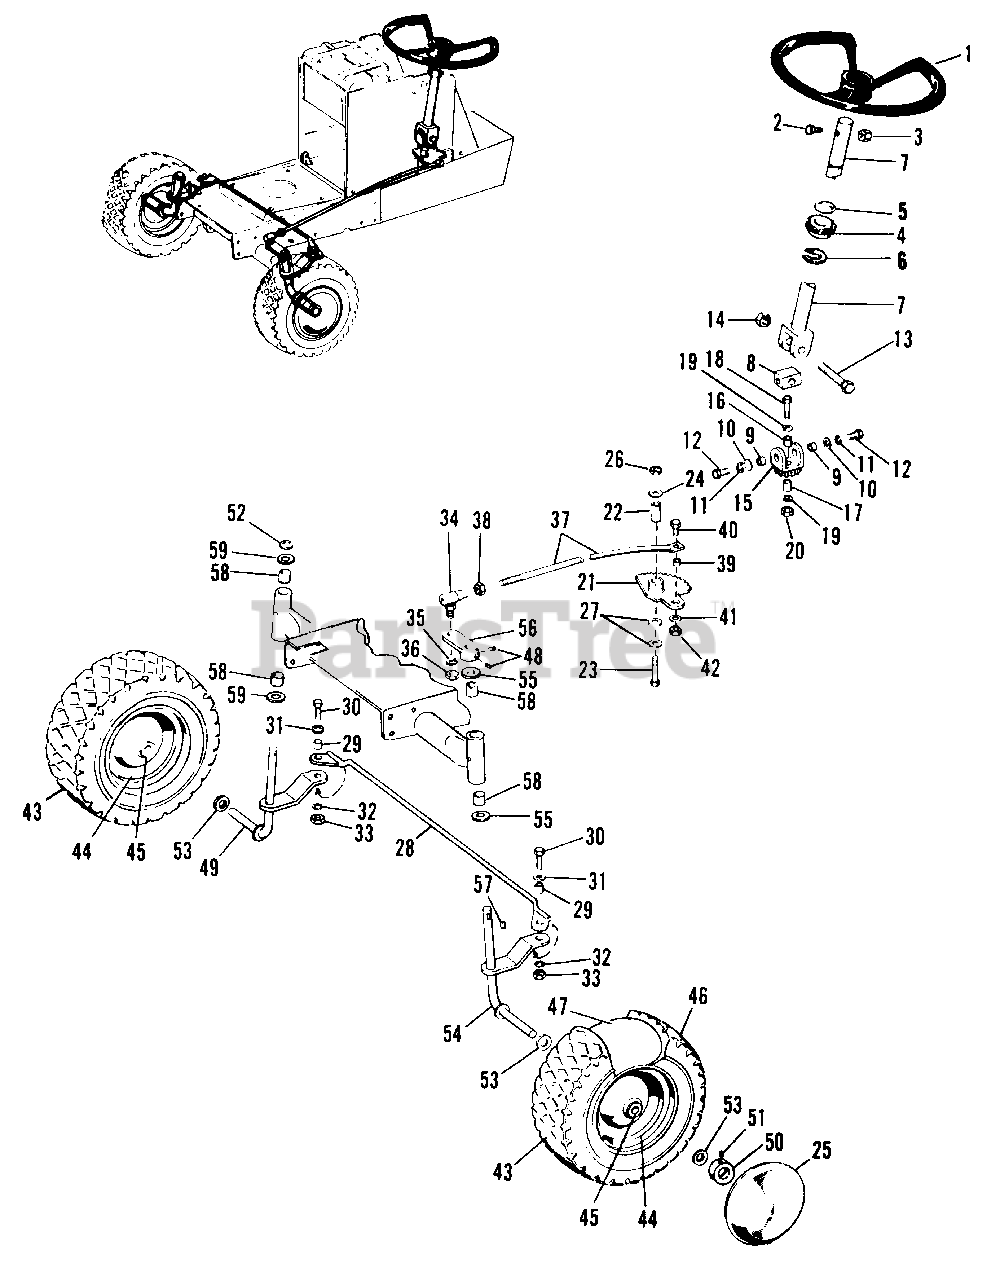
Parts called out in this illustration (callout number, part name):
1	Wheel Assembly, Steering
2	Capscrew, Hex, 5/16"-18 x 1-1/4" lg.
3	Nut, Hex, Full, Lock 5/16"-18
4	Bushing, Steering
5	Washer, (As Required)
6	Ring, Snap
7	Shaft Assembly, Steering
8	Pin, Universal Joint
10	Washer, Plain, 3/8"
11	Lockwasher, 3/8"
12	Capscrew, Hex, 3/8"-16 x 3/4" lg.
13	Capscrew, Hex, 5/16-18 x 1-1/2" lg.
14	Nut, Hex, Full, Lock 5/16"-18
15	Fork & Pinion Assembly
18	Capscrew, Hex, 3/8"-16 x 1-1/2" lg.
20	Nut, Hex, Lock, Jam, 3/8"-16
21	Gear Assembly, Steering
23	Capscrew, Hex, 3/8"-16 x 2-1/2" lg.
24	Washer, Plain, 3/8"
25	Cap, Hub, Front
26	Nut, Hex, Full, Lock, 3/8"-16
27	Washer, Special
28	Link Assembly, Drag
30	Screw, Special
31	Washer, Plain, 3/8"
32	Lockwasher, 3/8"
33	Nut, Hex, Full, 3/8"-16
34	Joint, Ball
35	Lockwasher, 1/2"
36	Nut, Hex, Full, 1/2"-20
38	Nut, Hex, Jam, 1/2-20
40	Capscrew, Hex, 3/8"-16 x 1" lg.
41	Washer, Plain, 3/8"
42	Nut, Hex, Full, Lock, 3/8"-16
43	Wheel & Tire Assembly
48	Screw, Set, 5/16"-18 x 1/2" lg.
49	Spindle Assembly, R.H.
50	Collar, Set
51	Screw, Set, 5/16"-18-5/16" lg.
52	Ring, Retaining
54	Spindle Assembly, L.H.
56	Lever Assembly, Steering
